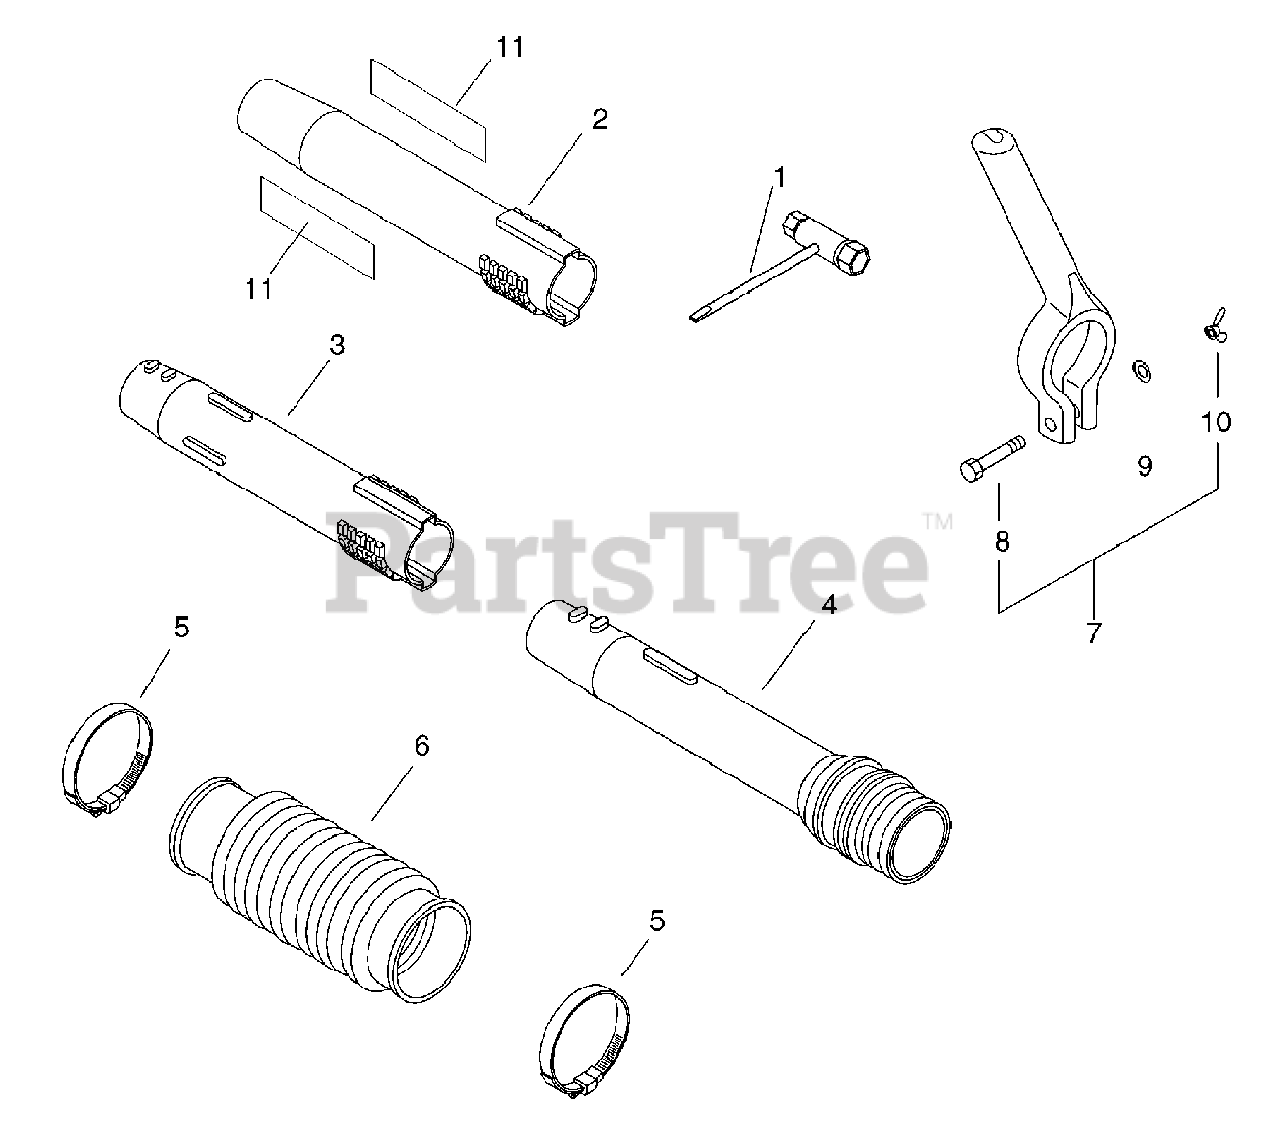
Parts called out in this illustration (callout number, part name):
1	T-WRENCH 13×19×180
2	TUBE, BLOWER - ROUND NOZZLE
3	TUBE, BLOWER - STRAIGHT
4	TUBE, BLOWER - SWIVEL
5	CLAMP 58.7 MM / 82.5 MM
6	TUBE, BLOWER - FLEXIBLE
7	HANDLE SET, FRONT
8	BOLT 6×45
9	WASHER 6.5×11.5×0.8
10	NUT, WING 6
11	LABEL, ECHO BLOWER TUBE
